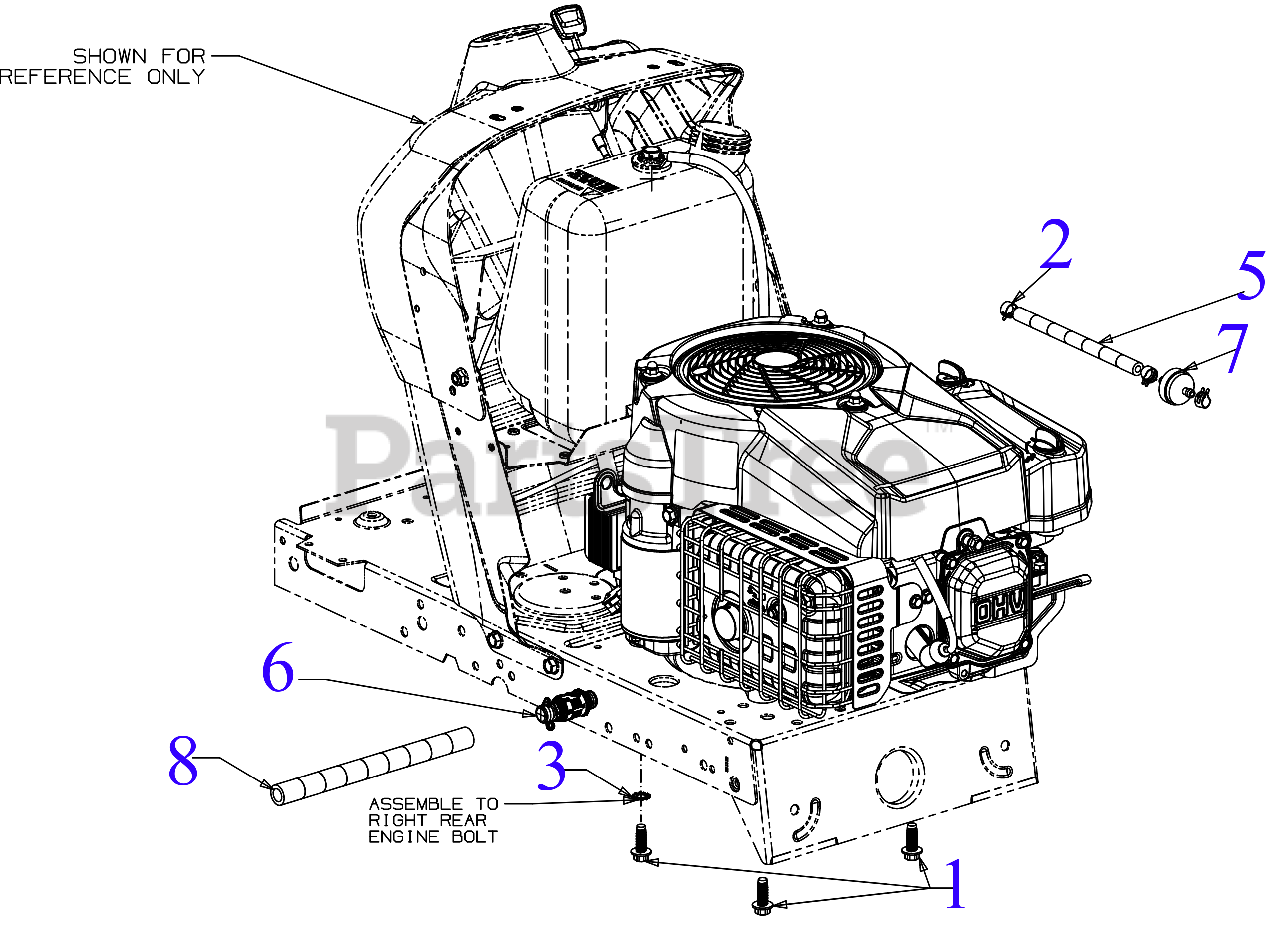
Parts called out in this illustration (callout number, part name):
1	SCREW 3/8-16 x 1
2	HOSE CLAMP 1/20
3	LOCK WASHER 3/8
5	FUEL HOSE LOW PERMEATION 13"
6	OIL DRAIN VALVE
7	FUEL FILTER
7	Genuine Factory Parts FUEL FILTER
8	DRAIN HOSE 14''
